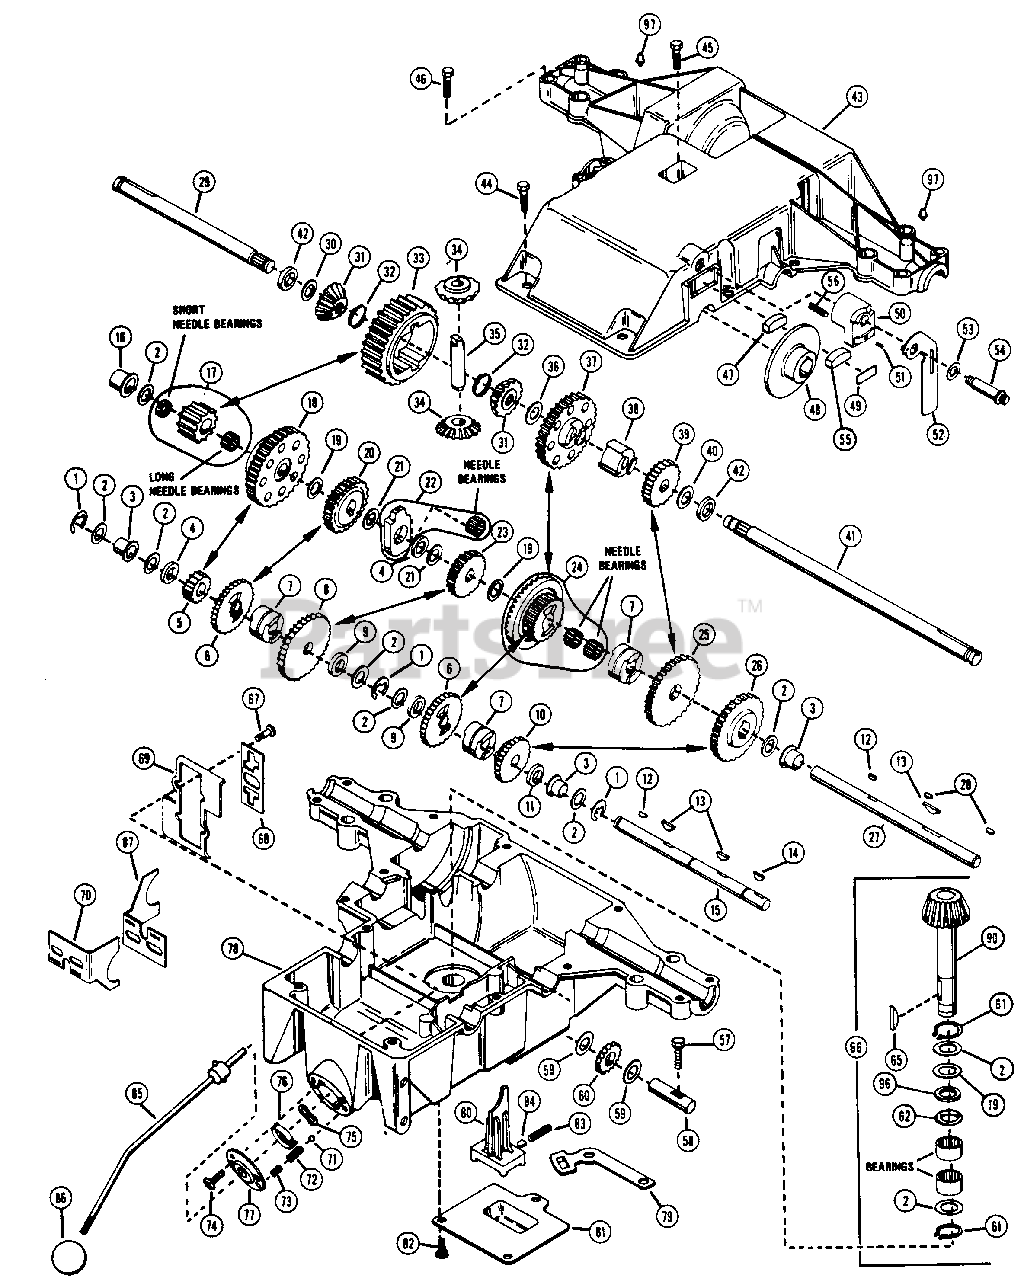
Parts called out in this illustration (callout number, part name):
1	SNAP RING
2	SHIM KIT
3	FLANGE BUSHING
4	SPACER
5	SPUR GEAR 13T
6	SPUR GEAR 25T
7	CLUTCH COLLAR
8	SPUR GEAR 30T
9	SPACER
10	SPUR GEAR 20T
11	WASHER .020
12	KEY, WOODRUFF .125X.50 HRD #3
13	HI-PRO KEY
14	KEY, WOODRUFF .187X.625 HRD #61
15	INTERMEDIATE SHAFT
16	FLANGE BEARING
17	GEAR ASSEMBLY 12T
18	SPUR GEAR 37T
19	WASHER, .045 THICK
20	SPUR GEAR 25T
21	WASHER .025
22	SHAFT SUPPORT ASSEMBLY
23	SPUR GEAR 20T
24	BEVEL GEAR ASSEMBLY
25	SPUR GEAR 33T
26	SPUR GEAR 30T
27	DRIVE SHAFT
28	WOODRUFF KEY
29	L. H. AXLE
30	SHIM KIT
31	SPLINED MITER GEAR 15T
32	SNAP RING
33	SPUR GEAR 32T
34	MITER GEAR 15T
35	CROSS SHAFT
36	WASHER .031
37	SPUR GEAR 35T
38	GEAR LOCK
39	SPUR GEAR 22T
40	WASHER, FLAT .938X1.750X.134
41	R. H. AXLE
42	FELT SEAL
43	LOWER HOUSING
44	BOLT, HEX 1/4-20X.875
45	MACHINE SCREW #12-24X.625
46	BOLT, HEX 1/4-20X1.25
47	FRICTION PUCK(INNER)
48	BRAKE DISC
49	SPACER
50	BRAKE JAW ASSEMBLY
51	SETSCREW, NO. 8-32
52	LEVER, ACTUATING ASSEMBLY
53	WASHER
54	SHOULDER BOLT
55	PUCK, FRICTION
56	COMPRESSION SPRING
57	SCREW, MACH. 10-24X1.25 PHD
58	IDLER SHAFT
59	WASHER .020 THICK
60	IDLER GEAR ASSEMBLY
61	SNAP RING
62	"O" RING
65	KEY, WOODRUFF 3/16X3/4 #9
66	INPUT SHAFT ASSEMBLY
67	BOLT, HEX 1/4-28X.75
68	LOCKOUT PLATE
69	FORK SUPPORT PLATE
70	SHIFTER FORK
71	DETENT BALL
72	DETENT SPRING
73	SCREW, SET 1/4-20X.375 H/SCK
74	SCREW, MACHINE 10-24X.50
75	WAVE WASHER
76	NYLON INSERT
77	COVER
78	UPPER HOUSING
79	HI-LO SHIFT LEVER
80	HI-LO SHIFTER FORK ASSEMBLY
81	HI-LO COVER PLATE
82	SCREW, MACH. 8-32X.50
83	DETENT SPRING
84	DETENT PIN
85	SHIFT LEVER ASSEMBLY
86	SHIFT KNOB
87	SHIFTER FORK
90	PINION AND SHAFT ASSEMBLY
96	WASHER .040 THICK
97	FITTING, LUBE 1/4-28
